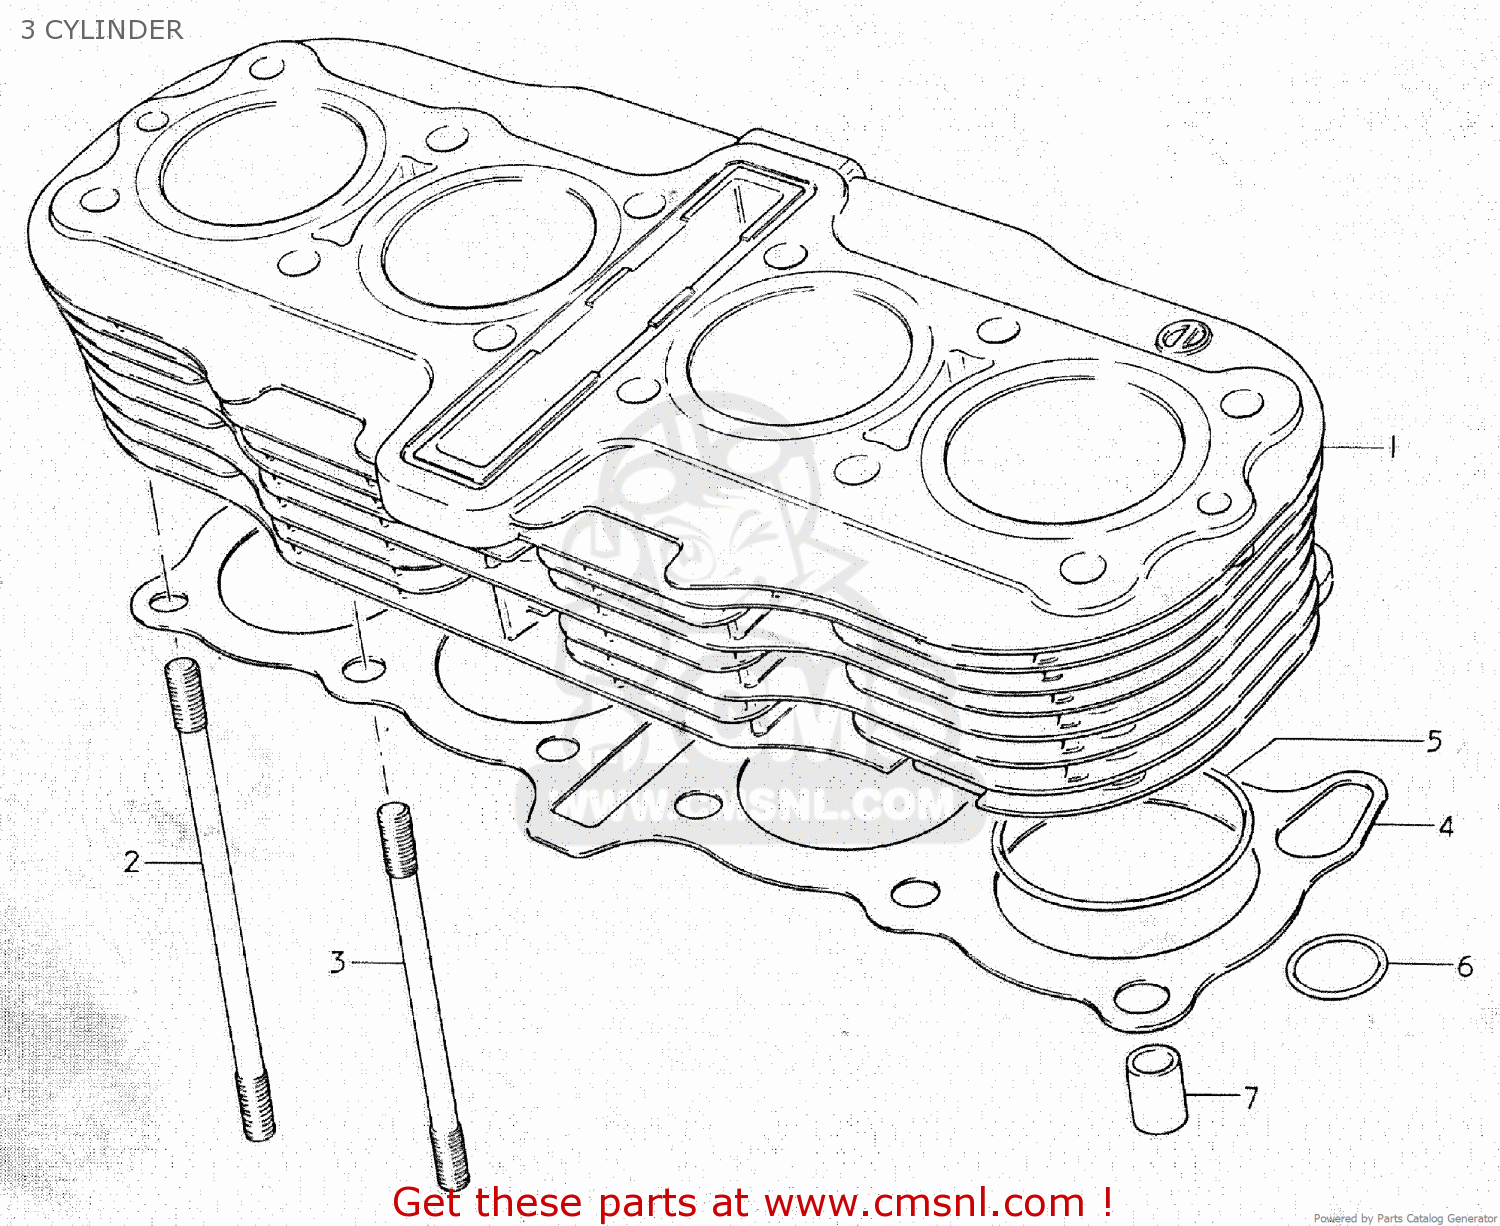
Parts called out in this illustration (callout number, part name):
1	CYLINDER
2	STUD
3	STUD
4	GASKET,CYLINDER (MCA)
5	O RING(D:2,ID:70)
6	O RING(D:3.05)
7	PIN
